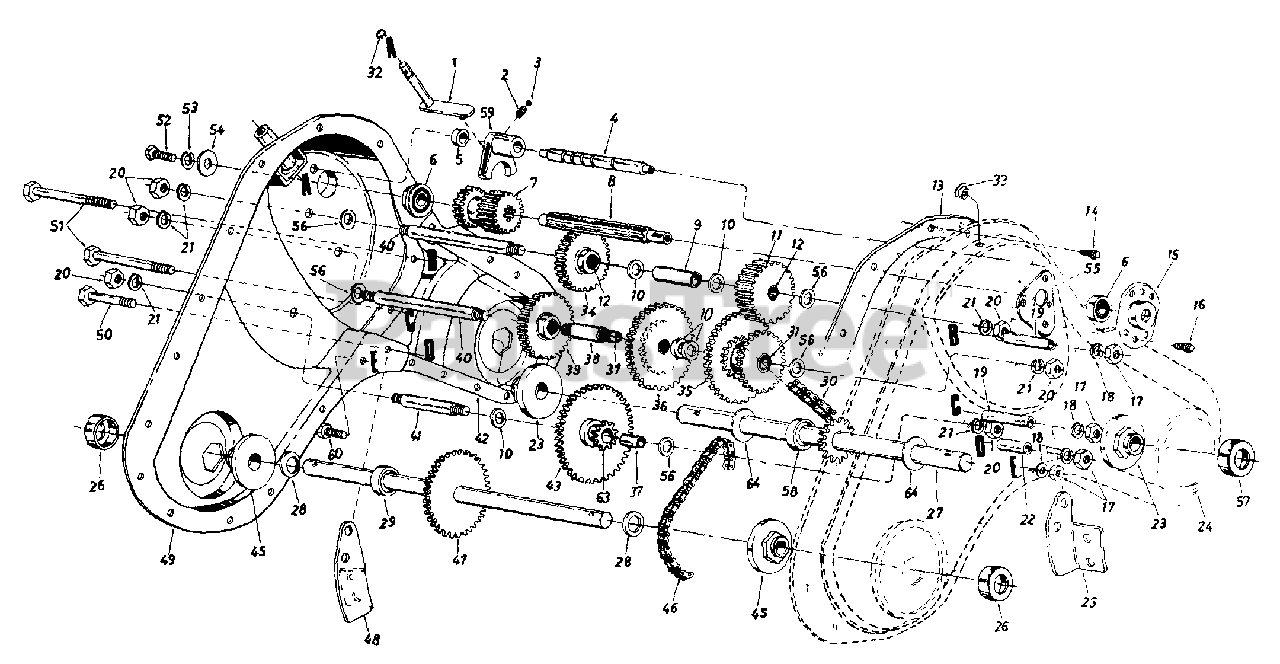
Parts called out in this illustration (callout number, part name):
1	Shifting Bracket Ass'y.
2	Compression Spring .50" Lg.
3	Ball Detent .250" Dia.
4	Detent Shaft 1/2" Dia.
5	Spacer.505" l.D. x.88" O.D.
6	Ball Brg ..62" I.D. x 1.38"
7	Spur Gear 167 (Input)
8	Input Spline Shaft 7/8"
9	Spacer .657" I.D. x 2.85" Lg.
10	FI-Wash..640" I.D. x 1.24"
11	Spur Gear 30T 7/8" I.D.
12	Needle Bearing 5/8" I.D.
13	Gasket -- Trans. Hsg.
14	Hex S-Tap Scr. 1/4-20 x .5"
15	1-3/8" Dia. Bearing Housing
16	Hex TT-Tap Scr. 1/4-20 x .75"
17	Hex Nut 5/16-18 Thd.
18	L-Wash. 5/16" I.Q.
19	Spacer 1.56" Lg.
20	Hex Nut 7/16-20 Thd.
21	Bell-Wash..45" I.D. x 1.0"
22	Spacer 1.015" Lg.
23	Tine Shaft Brg. 1.002 x 2.50
24	Trans. Housing Ass'y.-- L.H.
27	Tine Shaft Ass'y. 1" O.D.
28	FI-Wash..76" I.D. x 1.5" O.D.
29	Spacer .75" I D. x .50" Lg.
30	Chain #50 5/8 Pitch x 52 Links -- Endless
31	Needle Bearing 5/8" I.D.
32	Snap Ring
33	Taper Cap Plug
34	Spur Gear 30T 12/16" I.D.
35	30/44T Gear Ass'y. Comp.
36	Spur Gear 44T
37	Sleeve Bearing
38	Gear Hub 3/4" I.D. x 3" Lg.
39	Spur Gear 30T 1.0" I.D. x 1/2" W
40	Jack Shaft 5/8" Dia, x 5"
41	Jack Shaft 5/8" Dia. x 2.38"
45	Wheel Brg..752" x 2.5"
46	#420 Chain 1/2 Pitch x 50 Links -- Endless
47	Wheel Shaft Ass'y. 15.6"
51	Hex Bolt 5/16-18 x 2.5"
52	Hex Bolt 1/4-20 x .62" Lg.
53	L-Wash. 3/8" I.D.
54	Fl-Wash. 1/4" I.D. x .93" O.D.
55	Gear Positioner Bracket
56	Fl-Wash. 7/16" I.D. x 1-3/8"
57	Dust Cover Ass'y 1" Shaft
58	Spacer 1" I D. x 2" 0 D.
59	Shifting Fork
60	Hex Bolt 5/16-18 x 75" Lg.
63	10T Sprocket Ass'y.
64	Thrust Wash. 1.03" I.D. x 1.62" O.D.
